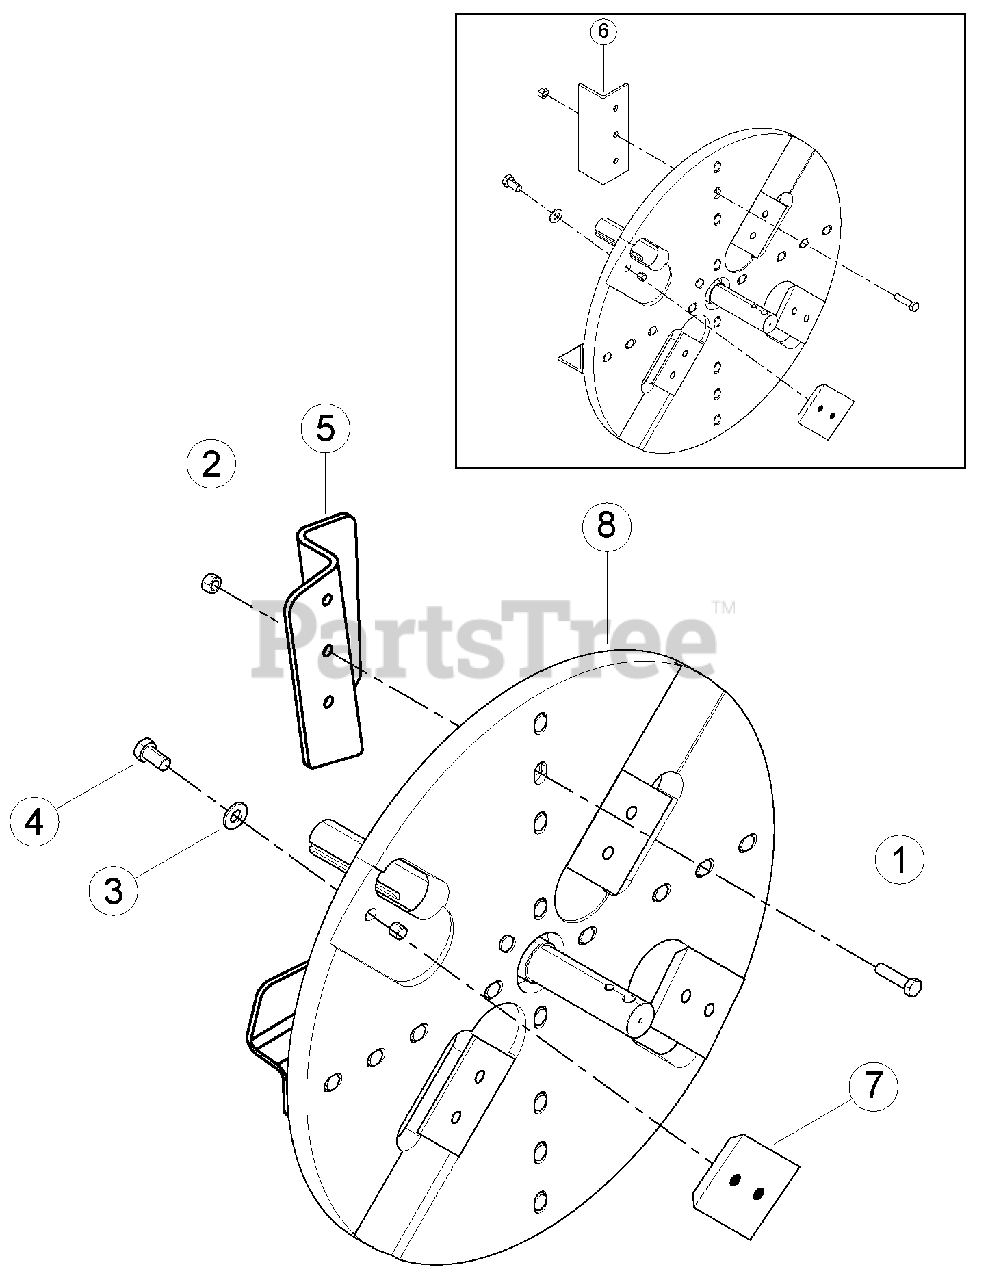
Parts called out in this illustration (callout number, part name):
1	BOLT, 1/2 X 2 HEX HD GR5 ZP
2	NUT, 1/2 CENTERLOCK GRB ZP
3	WASHER, 5/8 SAE HARDENED
4	BOLT, M16 X 2.0 X 30 HEX HD W/PATCH
5	PADDLE, BIG CHIPPER
8	ASSEMBLY, 9 INCH CHIPPER DISK
